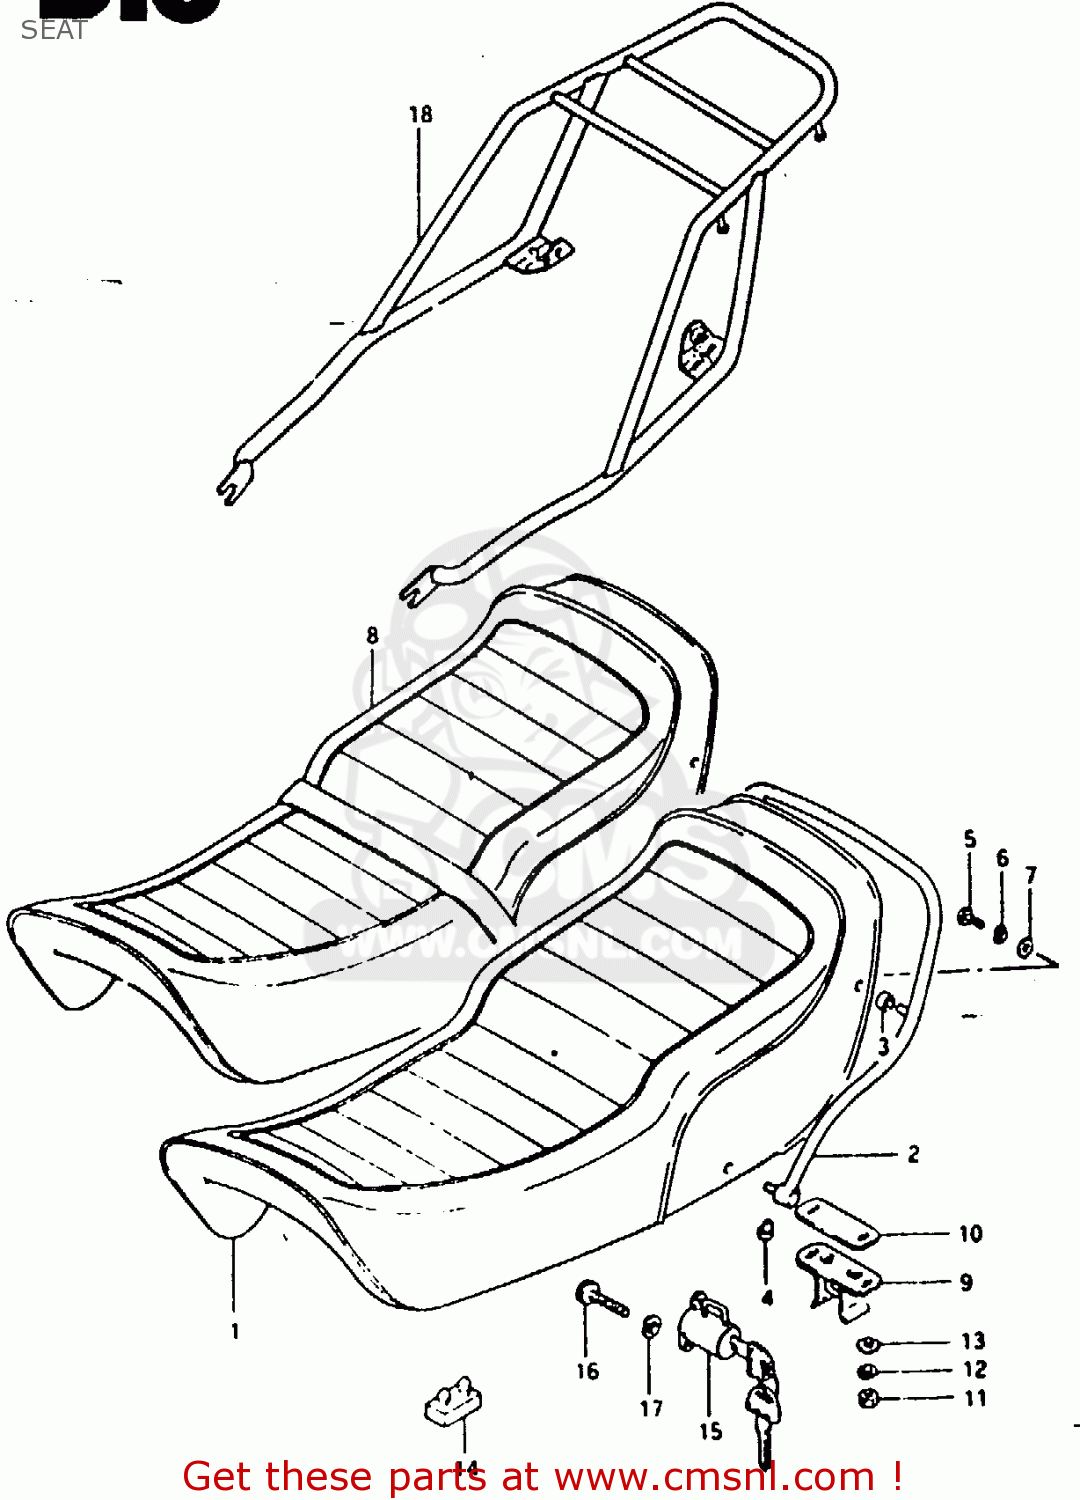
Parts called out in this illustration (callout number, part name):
1	SEAT ASSY (BLACK)
2	HANDLE,PILLION RIDER
3	CUSHION
4	END,SHEET HANDLE
5	BOLT
6	LOCK WASHER
7	WASHER
9	STRIKER, SEAT LOCK
10	SHIM,SEAT LOCK STRIKER
11	NUT
12	LOCK WASHER
13	WASHER
14	CUSHION
15	LOCK ASSEMBLY,HELMET
16	BOLT
17	LOCK WASHER
18	CARRIER
